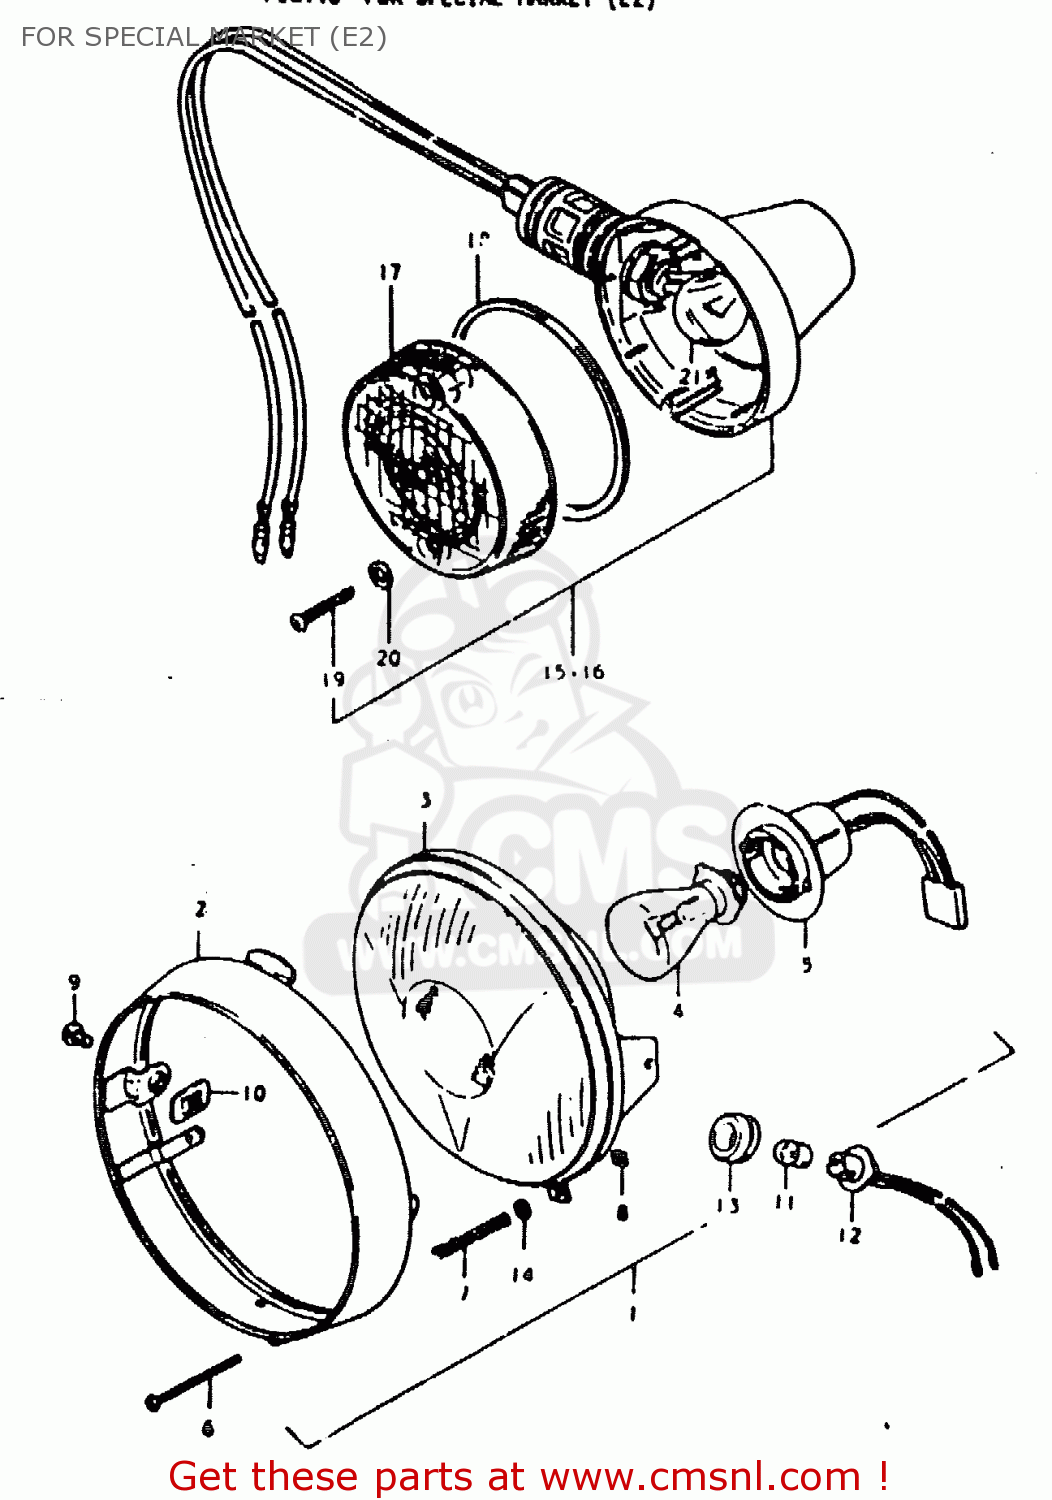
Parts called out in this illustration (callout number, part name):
1	HEADLAMP ASSY
2	RIM
3	UNIT
4	BULB(6V25/25W,STANLEY,A7007)
5	SOCKET,HEADLAMP
6	SCREW,HEADLAMP ADJUST
7	SPRING
8	NUT,HEADLAMP ADJUSTER
9	SCREW
10	NUT
11	BULB(6V/3W)
12	SOCKET
13	SEAL,PARKING BULB
14	WASHER
15	LAMP ASSY, REAR TURN SIGNAL
16	LAMP ASSY, REAR TURN SIGNAL
17	LENS
18	GASKET (NAS)
19	SCREW TAPP.
20	GASKET (NAS)
21	BULB (6V,18W)
